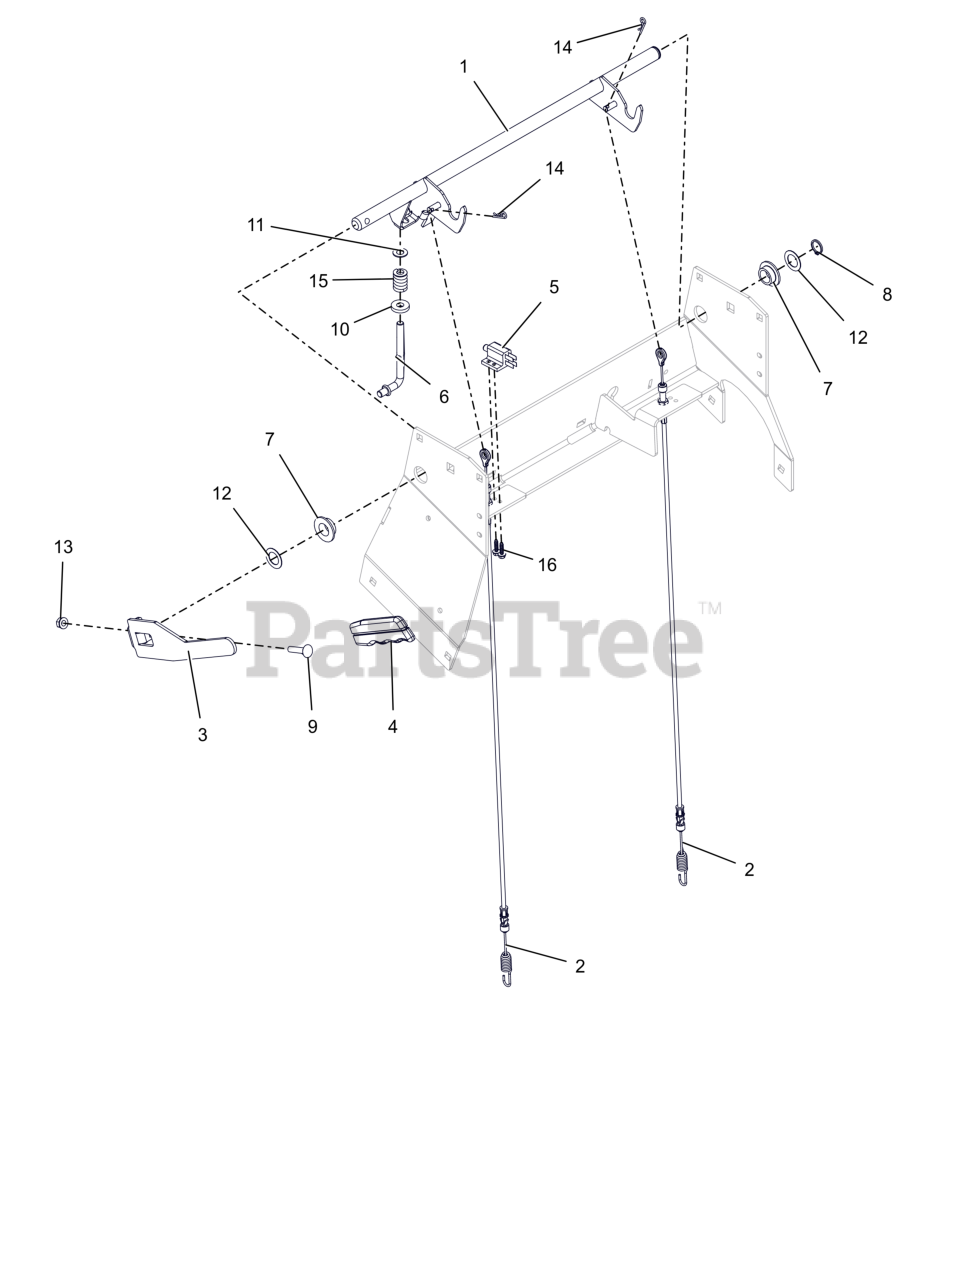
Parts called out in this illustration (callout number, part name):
1	WLDMT, PARKING BRAKE SHAFT (BLACK)
2	CABLE, BREAK - PROSTANCE
3	HANDLE, PARK BRAKE (BLACK)
4	GRIP, PARKING BRAKE (YELLOW)
5	SWITCH- DOUBLE POLE N.O./N.O.
6	LINK, OVER CENTER BRAKE
7	BSHG-FLG .762X1.48X.44 NYL
8	RG-RTNG-EXT .689X.078
9	BLT,RHSN .31-18X1.50 G5 ZCC
10	WSHR, FLT .406X1.00X.188 ZCC
11	WSHR-FL-STL 0.406X0.812X0.055 HRD
12	WSHR-FL-STL 0.76X1.225X0.032 ZCC
13	NUT,LK-CTR-FLG .31-18 GF ZCC
14	PIN, HAIR #213 .08X1.19 ZCC
15	SG-COMP .187X.56X1.62
16	SCR, PLASTITE-HWH 0.2 X 0.75 ZC120
